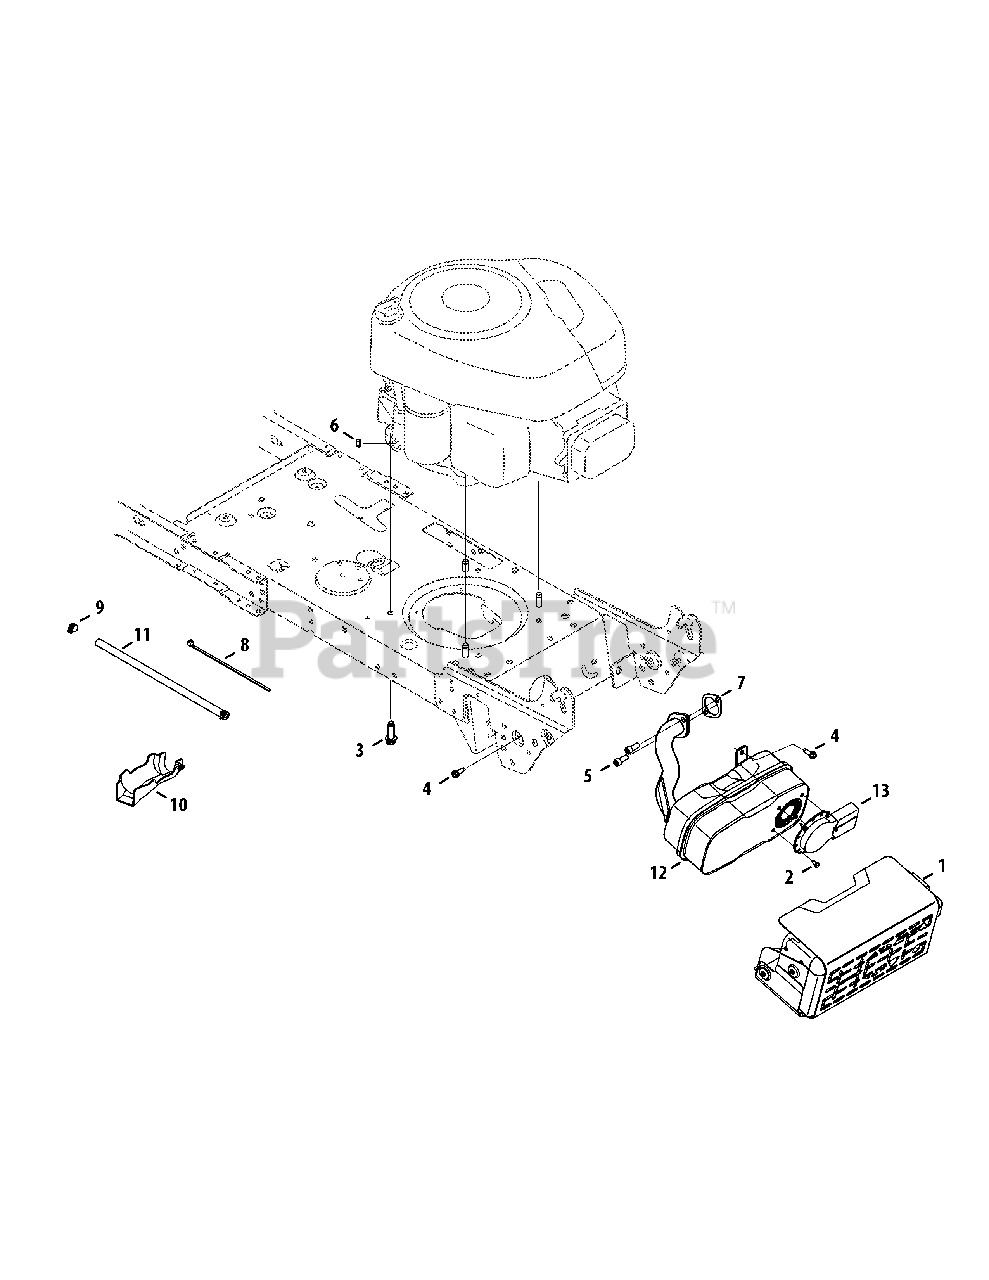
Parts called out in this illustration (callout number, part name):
1	Muffler Shield
2	Screw, #8-18 x .500
3	Tap Screw, 3/8-16 x 1.000
4	Tap Screw, 1/4-20 x 7.50
5	SOC Head Screw, 5/16-18 x .750
6	SEMS Nut, 1/4-20
7	Exhaust Gasket
8	Cable Tie
9	Hose Clamp, .490 Dia.
10	Oil Drain Sleeve
11	Fuel Hose, 1/4
12	Muffler
13	Muffler Deflector
